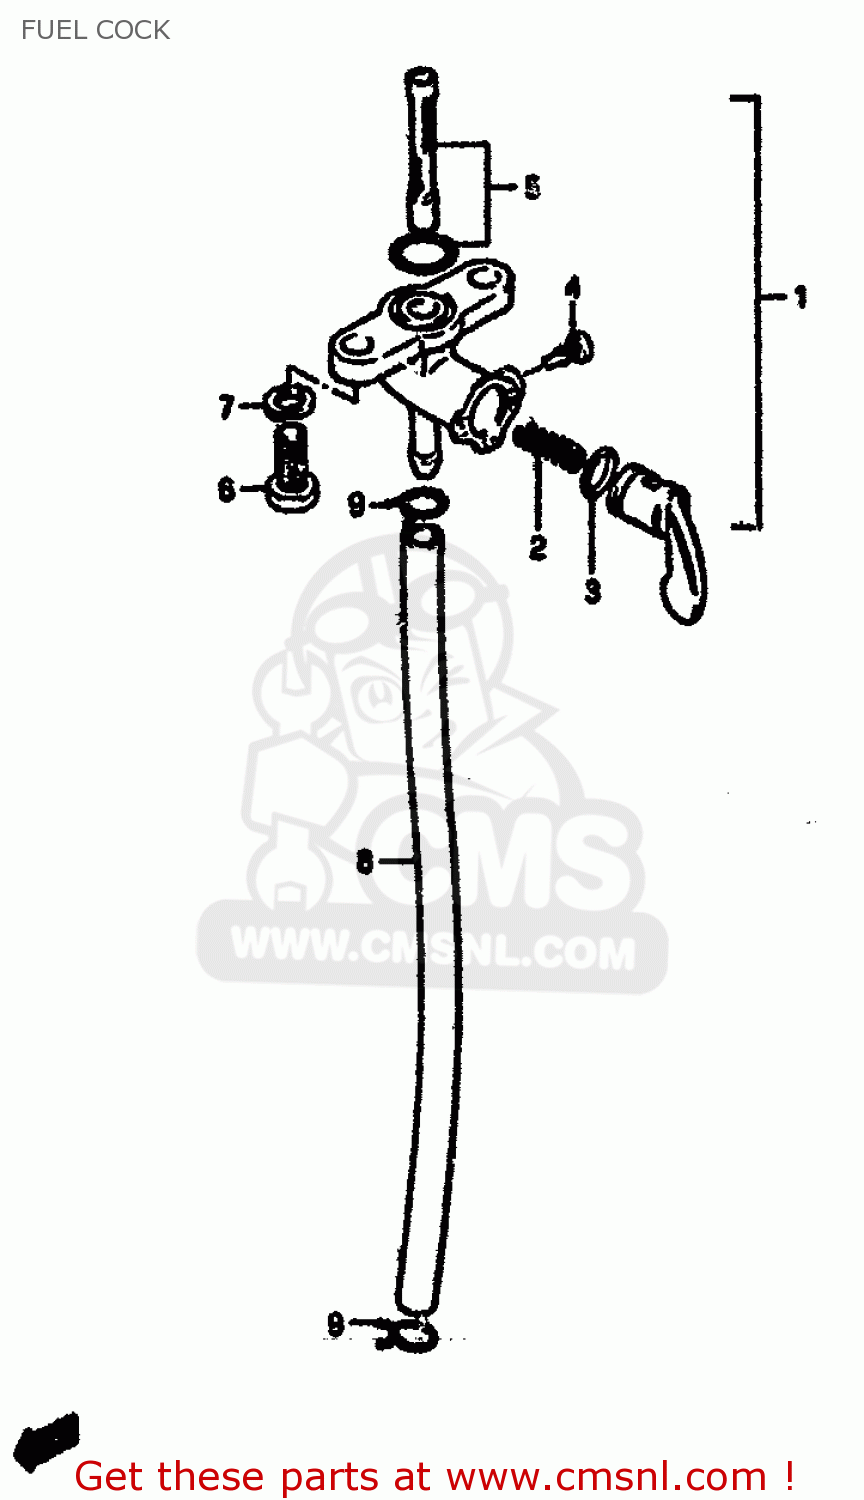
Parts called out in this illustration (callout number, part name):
1	COCK ASSY,FUEL
2	SPRING,FUEL COCK VALUE
3	O RING,LEVER
4	SCREW
5	FILTER SET FUEL
6	SCREW
7	LOCK WASHER
8	HOSE,FUEL
9	CLAMP
